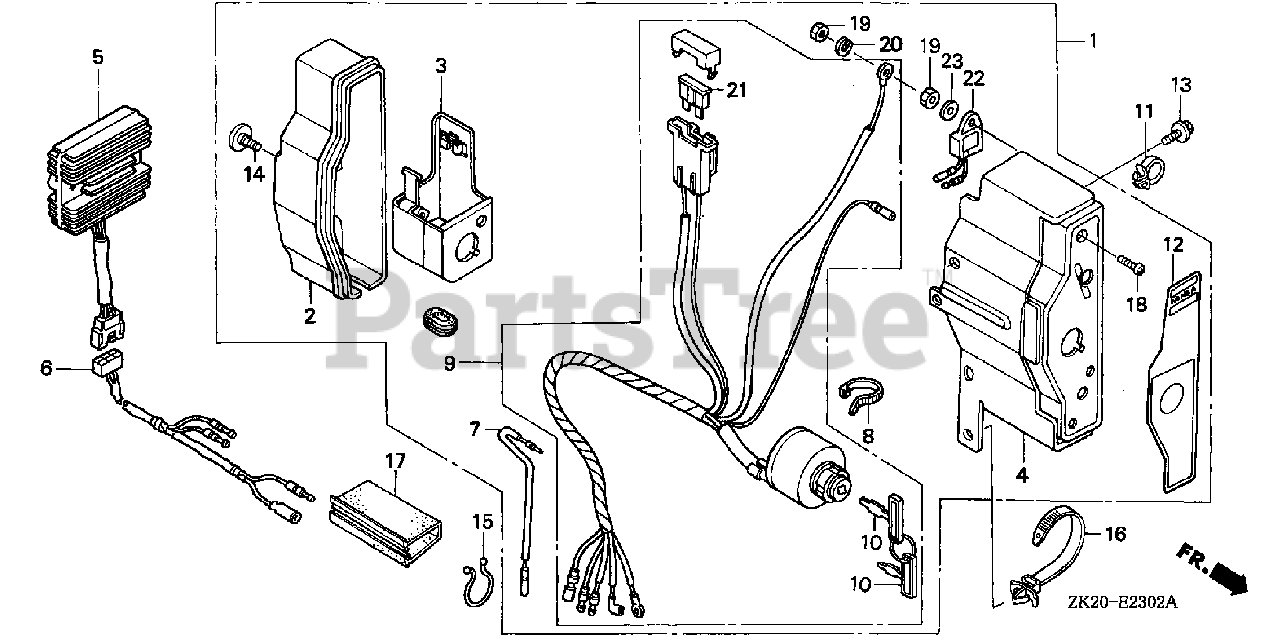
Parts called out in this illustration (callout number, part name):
1	BOX ASSY., CONTROL (EXTERNAL-ALERT 18A) *NH1* (BLACK)
1	BOX ASSY., CONTROL (EXTERNAL-ALERT 18A) *R8* (BRIGHT RED)
2	CASE, CONTROL
3	BRACKET, CASE MOUNTING
4	PANEL, CONTROL *R8**R8* (BRIGHT RED)
5	RECTIFIER ASSY., REGULATOR (20A)
6	SUB-WIRE HARNESS ASSY.
7	SUB-HARNESS
8	BAND
9	SWITCH ASSY., COMBINATION (18A-CHARGE)
10	KEY
11	HOLDER, STOP SWITCH WIRE
12	MARK, CONTROL BOX (EXTERNAL-REGULATOR)
13	BOLT, FLANGE (6X12) (CT200)
14	SCREW, SPECIAL (6X12)
15	CLIP, PURSE LOCK
16	STRAP, CABLE (118MM) *NH1L* (BLACK)
17	TUBE, FASTENER (30)
18	SCREW, PAN (4X12)
19	NUT, HEX. (4MM)
20	WASHER, SPRING (4MM)
21	FUSE, BLADE (25A)
22	ALERT UNIT, OIL
23	WASHER, PLAIN (4MM)
